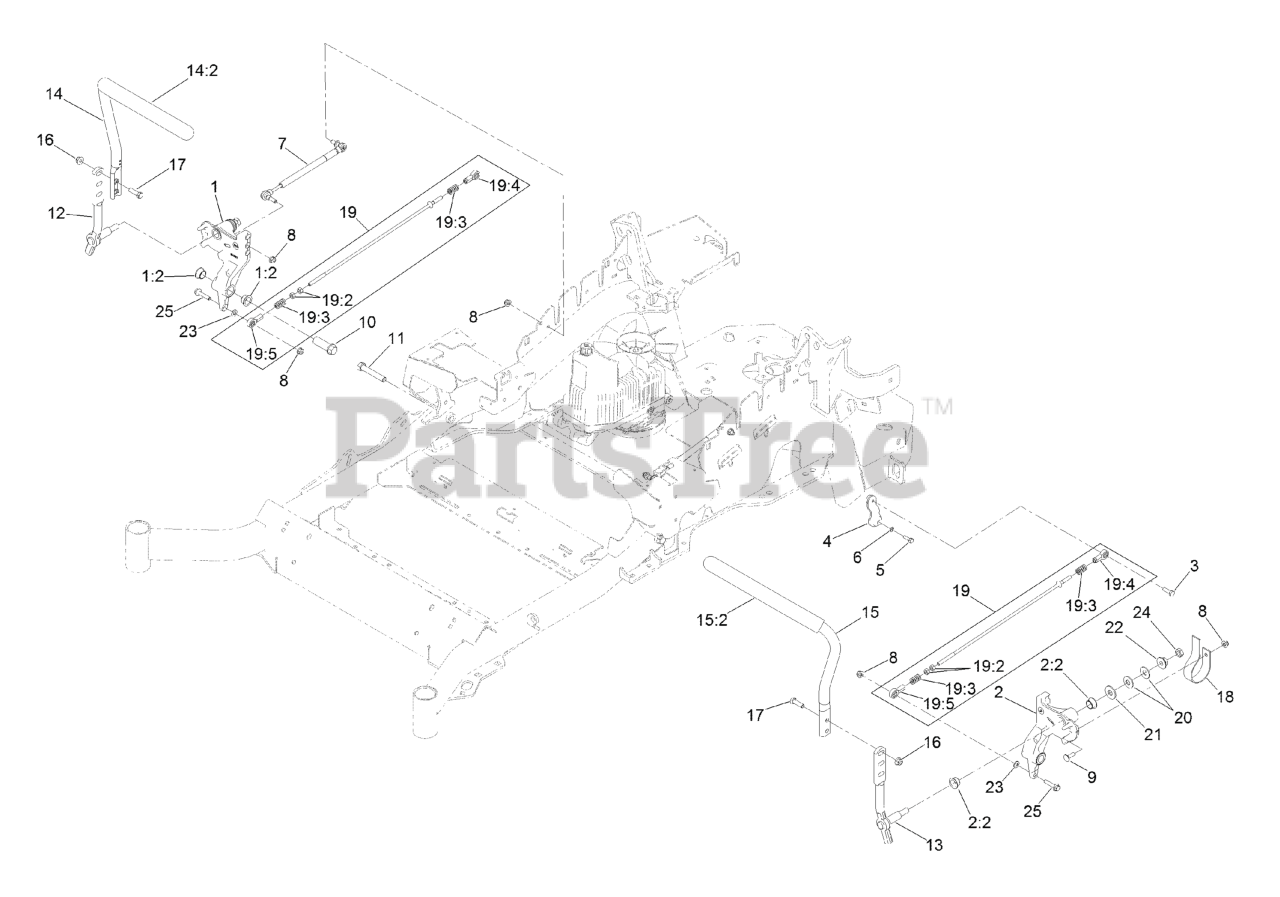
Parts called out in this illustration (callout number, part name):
1	RH MOTION CONTROL AND BUSHING ASM
1:2	BUSHING-FLANGE
2	LH MOTION CONTROL AND BUSHING ASM
2:2	BUSHING-FLANGE
3	SCREW-HH, THREAD LOCKING
4	ARM-CONTROL, PUMP
5	SCREW-HH
6	WASHER-SPRING
7	DAMPER-CONTROL, MOTION
8	NUT-HF, NI
9	BOLT-CARR
10	HUB-THREADED
11	SCREW-HH
12	LEVER-CONTROL MOTION, RH
13	LEVER-CONTROL MOTION, LH
14	RH STEERING HANDLE ASM
14:2	GRIP-LEVER, CONTROL
15	LH STEERING HANDLE ASM
15:2	GRIP-LEVER, CONTROL
16	NUT-HF, NI
17	SCREW-HH
18	SPRING-LEAF
19	FRONT PUMP LINKAGE ASM
19:2	NUT-HEX
19:3	SPRING-COMPRESSION
19:4	BALLJOINT-LH
19:5	BALLJOINT-RH
20	WASHER-SPRING
21	WASHER-FLAT
23	WASHER-PLAIN
24	NUT-JAM
25	SCREW-HHF
